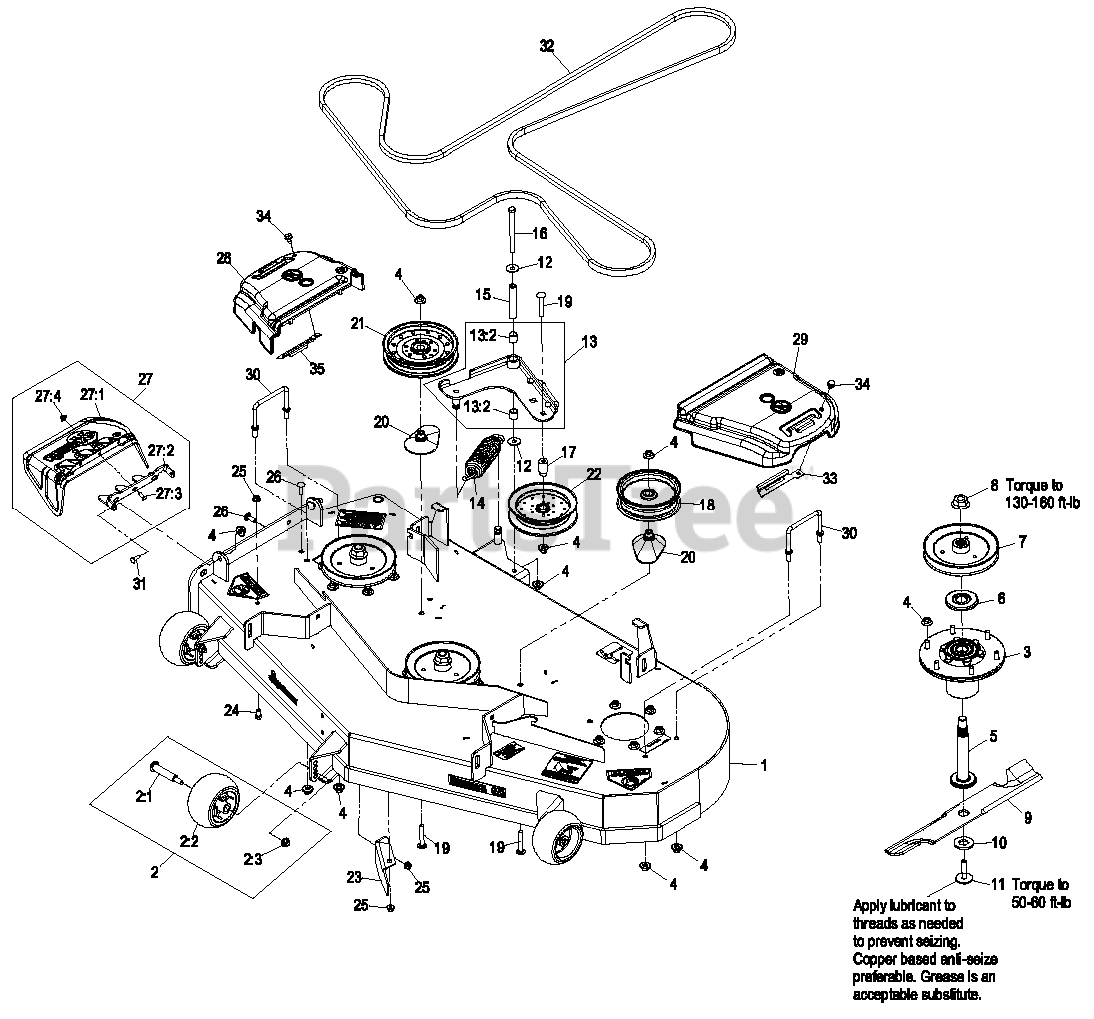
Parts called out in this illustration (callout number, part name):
1	DECK ASM-W/DECALS, 52
2	ANTI-SCALP ROLLER KIT
2:1	BOLT-SHOULDER
2:2	ROLLER-SCALP, ANTI
2:3	NUT-HF, NI
3	ASM,CUTTER HOUSING W/BEAR
4	Nut-Nyloc 3/8-16 Flg
5	SPINDLE,HEX PILOT 5.5" DE
6	GUARD,BEARING TOP .989
7	SHEAVE,BLADE DRIVE 6.50
8	NUT-FLANGE
10	WASHER-BLADE DRIVE
11	BOLT-BLADE, SEM
13:2	SLEEVE-BEARING
15	BUSHING-TIGHTENER, PIVOT
16	SCREW-HH
17	BUSHING,IDLER
19	BOLT-CARR, SHORT NECK
20	SPACER-PULLEY
23	BAFFLE,DISCHARGE 52/60
24	SCREW-HH
25	NUT-HF, NI
26	SCREW-CARR
27	ASM,DISCHARGE CHUTE
27:1	CHUTE,DISCHARGE
27:2	BRACKET,DISCHARGE CHUTE
27:3	SCREW-CARR
27:4	Nut-Nyloc 3/8-16 Flg
28	COVER-BELT, RH
29	COVER-BELT, LH
30	WIREFORM-COVER
31	BOLT-CARR
32	BELT-B162.50
33	RETAINER,COVER LH
35	RETAINER,COVER RH
